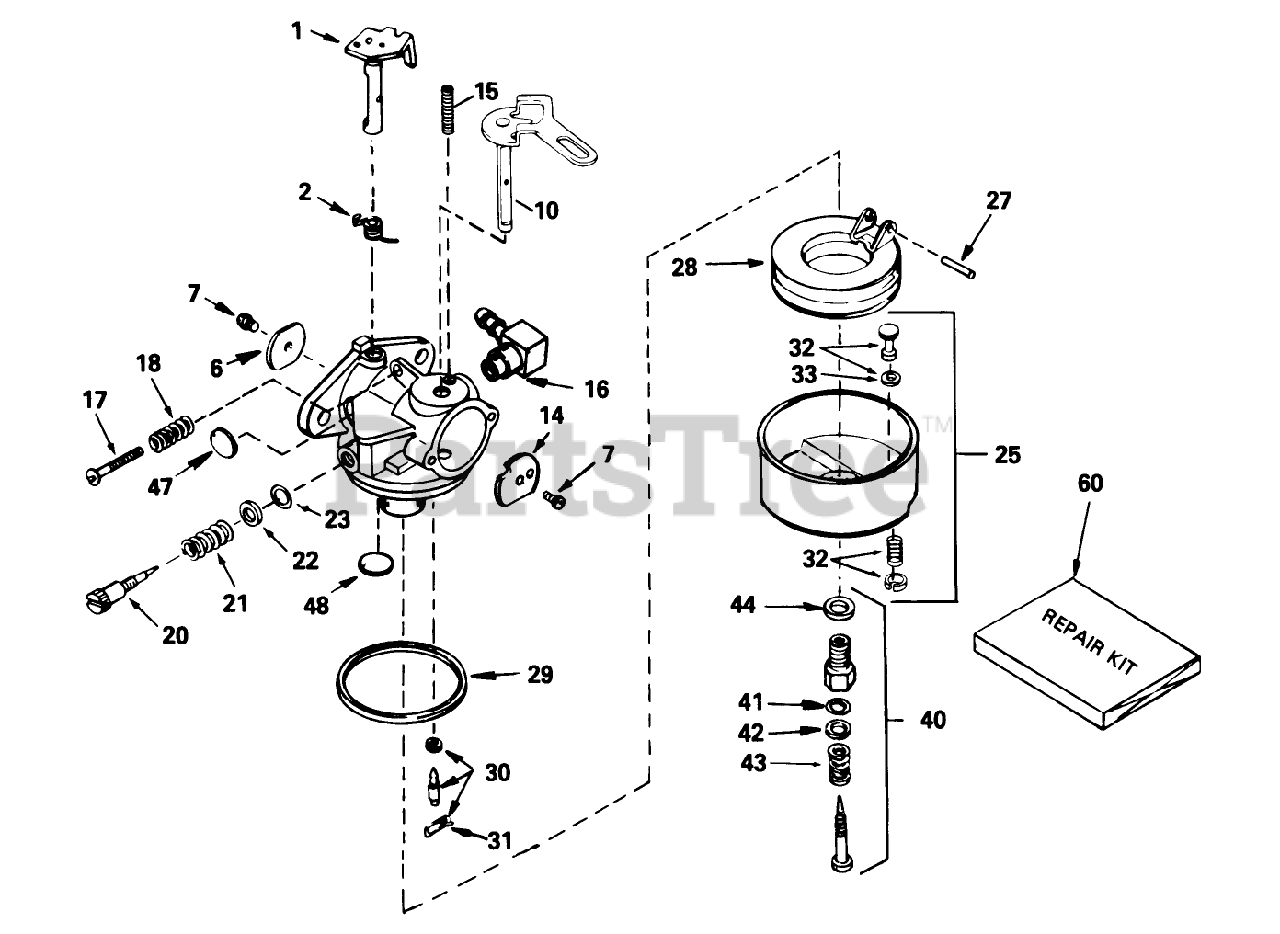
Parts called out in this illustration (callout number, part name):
1	Throttle Shaft and Lever ASM
2	Spring-Return, Throttle
6	Shutter-Throttle
7	Screw-Shutter
10	Choke Shaft and Lever Asm
14	Shutter-choke
15	Spring-Positioning, Choke
16	Fitting-Fuel
17	Screw-Throttle Crack Screw / Idle Speed
18	Spring-Tension
20	Screw-Idle
21	Spring-Tension
22	Washer
23	ORing
25	Float Bowl Asm. (Incl. Ref. # 32, 33)
27	Shaft-Float
28	Float
29	O Ring-Bowl, Float
30	Inlet Needle, Seat Clip Assy. (Incl. No. 13)
31	Clip-Spring
32	Bowl Drain ASM
33	Gasket-Plunger, Drain
40	Adjustment Screw Assy., Main (Incl. Nos. 5A, 21 23)
41	ORing
42	Washer
43	Spring
44	Washer-Bowl Nut
47	Plug-Welch, Idle Mixture Well
48	Plug-Welch, Atmospheric Vent
60	Repair Kit (Incl. items marked *)
